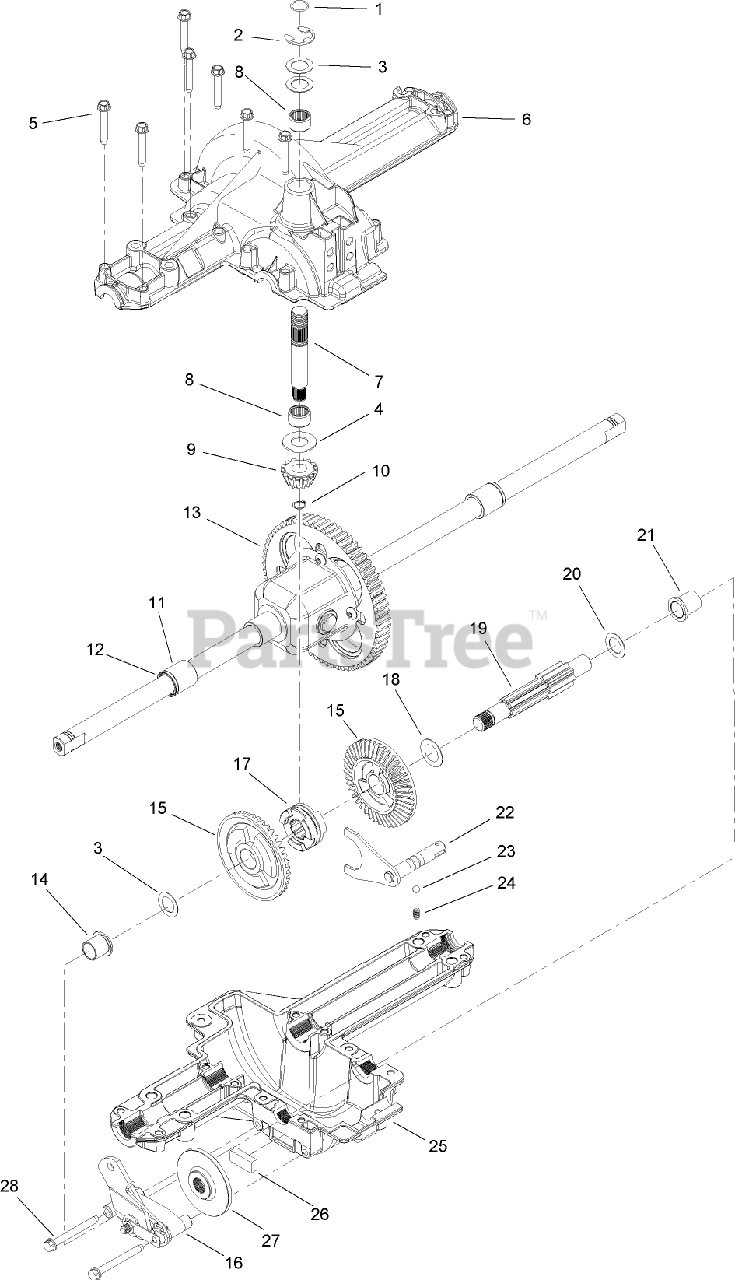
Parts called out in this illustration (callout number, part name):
1	RING-WIRE
2	RING-E
3	WASHER-FLAT
4	WASHER-THRUST
5	SCREW-TAP
6	HOUSING-UPPER
7	SHAFT-INPUT
8	BEARING-NEEDLE
9	PINION-INPUT, 14T
10	RING-SNAP
13	DIFFERENTIAL ASM
14	BEARING-FLANGE
15	GEAR-BEVEL, 42T
16	BRAKE ASM
17	COLLAR-CLUTCH
18	WASHER-FLAT
20	WASHER-THRUST
21	BEARING-FLANGE
22	SHIFT FORK ASM
23	BALL-DETENT
24	SPRING-DETENT
25	HOUSING-LOWER
26	PUCK-BRAKE
27	DISC-BRAKE
28	SCREW-HWH
